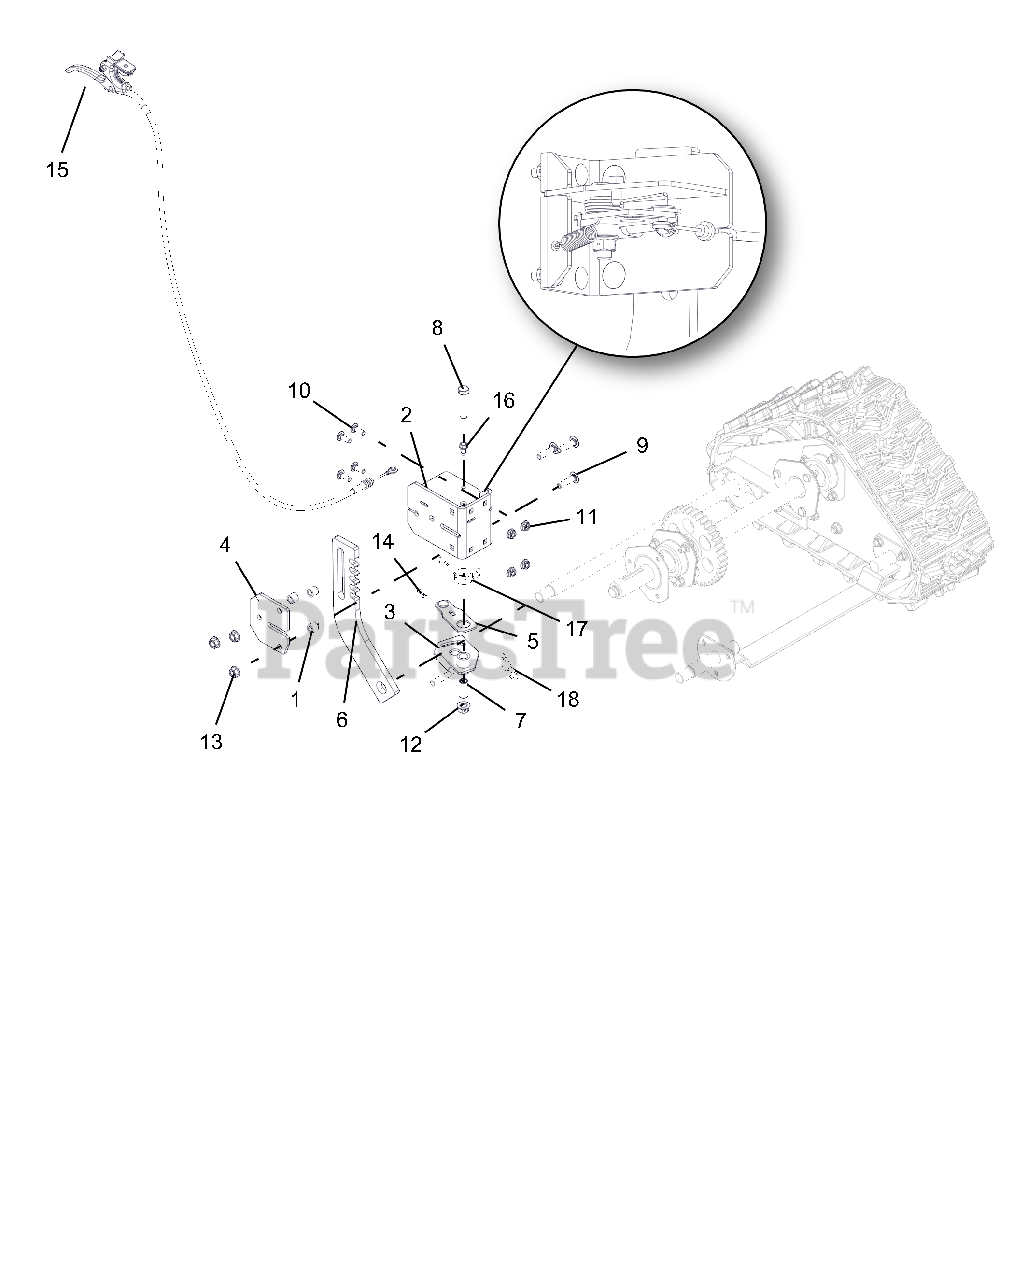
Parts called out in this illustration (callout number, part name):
1	SPACER .50 X .32 X .42
2	BRACKET, HEIGHT ADJUSTER
3	LOCK, HEIGHT ADJUSTER
4	PLATE, HEIGHT ADJUSTER
5	ARM, OVERTRAVEL
6	STOP, HEIGHT ADJUSTER-CPT BLAC
7	BSHG-SLV .385X.500X1.045
8	@BLT-HEX .38-16X1.75 GR5 YWZC
9	@BLT-RHDSHSQNK.31-18X1.25 G5YZ
10	@BLT-RDHDSQNK .25-20X.75 G5YZ
11	@NUT-LK-CTR-FLG .25-20 YWZC
12	NUT-LK-CTR-FLG .38-16 YWZC
13	@NUT-LK-TOP-FLG .31-18 YWZC
14	PIN-HAIR INT .06X.18X.77
15	CABLE, TRACK REMOTE
16	SCR-TAP .25-20X.50 HWH TR YWZ
17	SG-TORS .067X.88
18	SPRING-EXT .047 X .438 X 1.85
